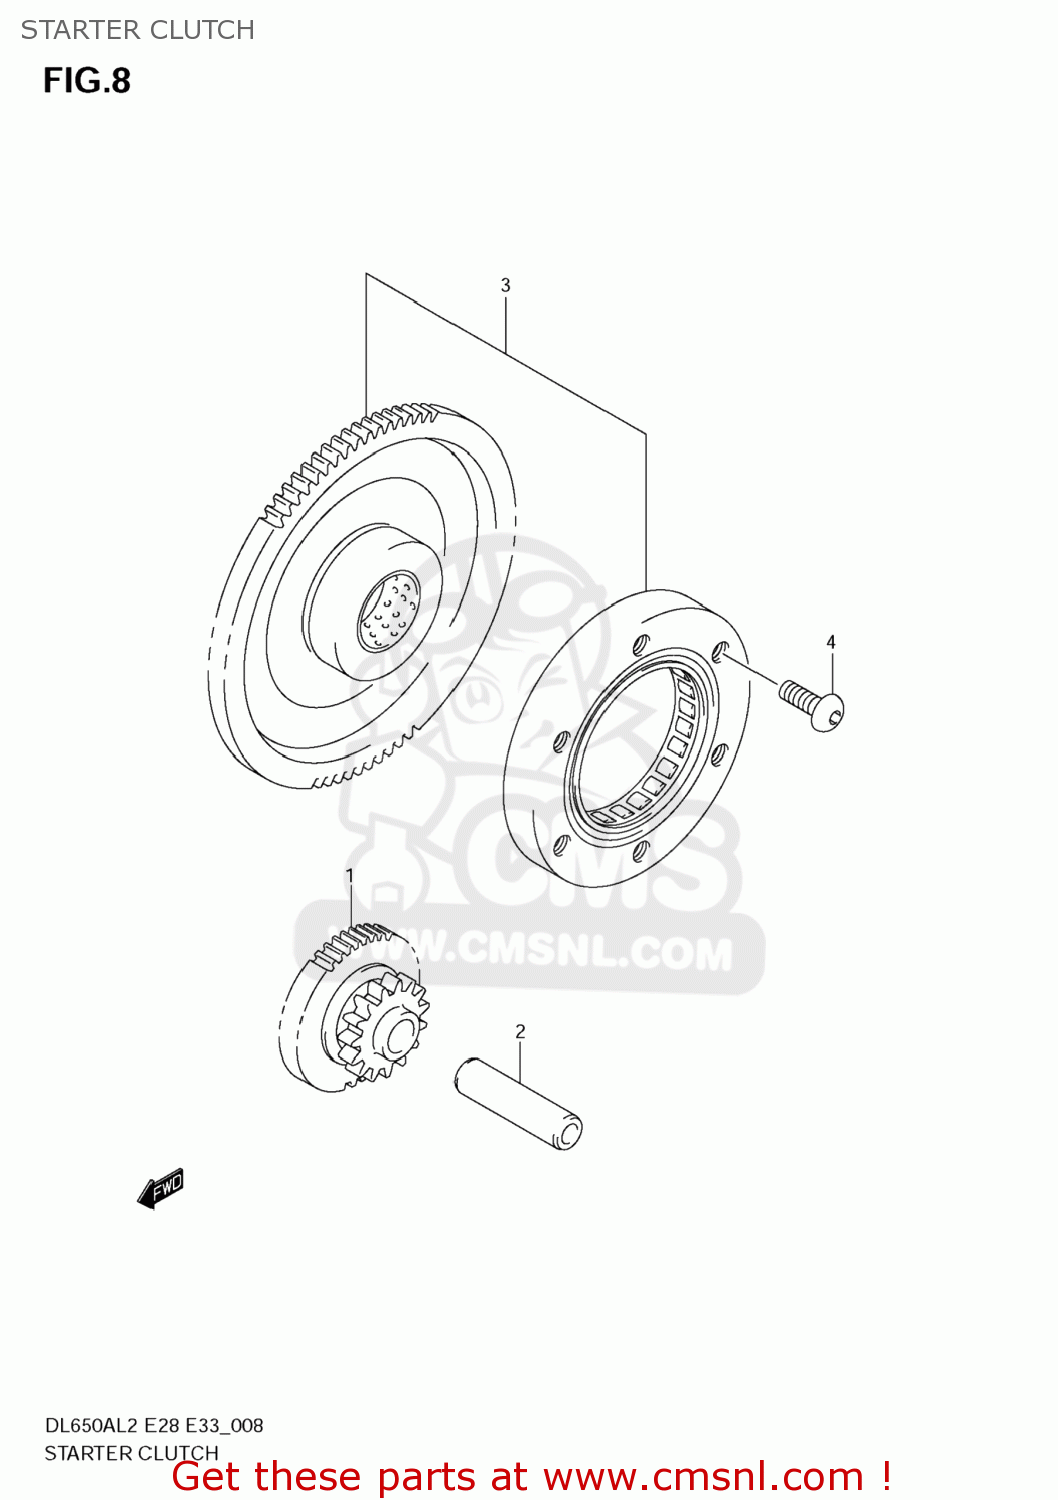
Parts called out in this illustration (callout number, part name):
1	GEAR,STARTER IDLE
2	PIN(8X12X45.5)
3	CLUTCH SET,STARTER
4	SCREW(8X16)
